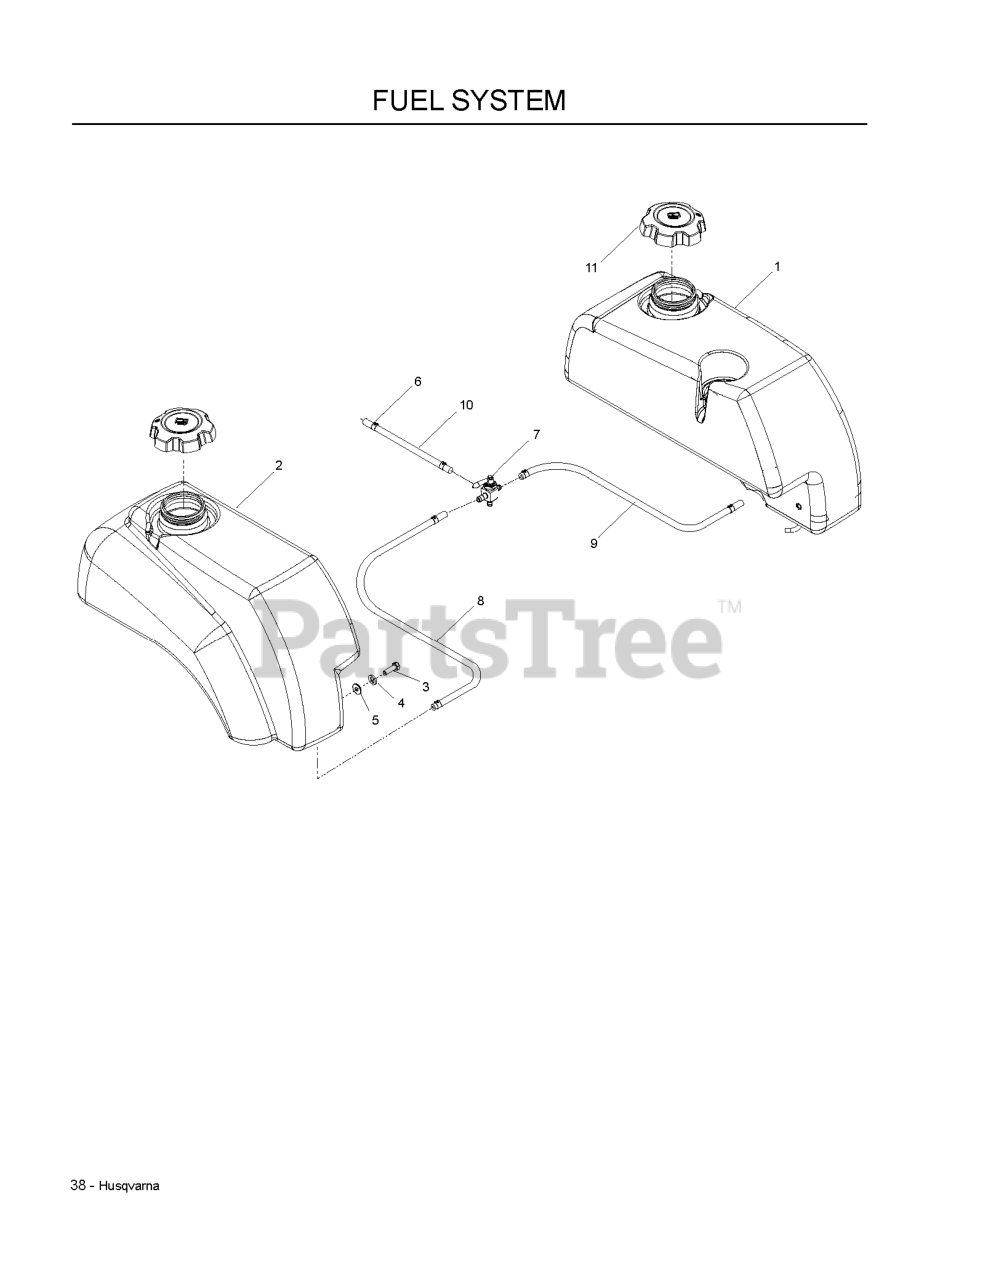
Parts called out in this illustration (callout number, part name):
1	LEFT TANK W/CUP HOLDER
2	FUEL TANK RT
3	HCS 5/16C X 3/4
4	WASHER.LOCK.HVY.HLCL.SPR.5/16
5	WASHER 5/16 FLAT
6	HOSE CLAMP
7	FUEL VALVE
8	FUEL LINE 24"
9	HOSE 1/4 X 28
10	FUEL LINE 13"
11	FUEL CAP, HTC
